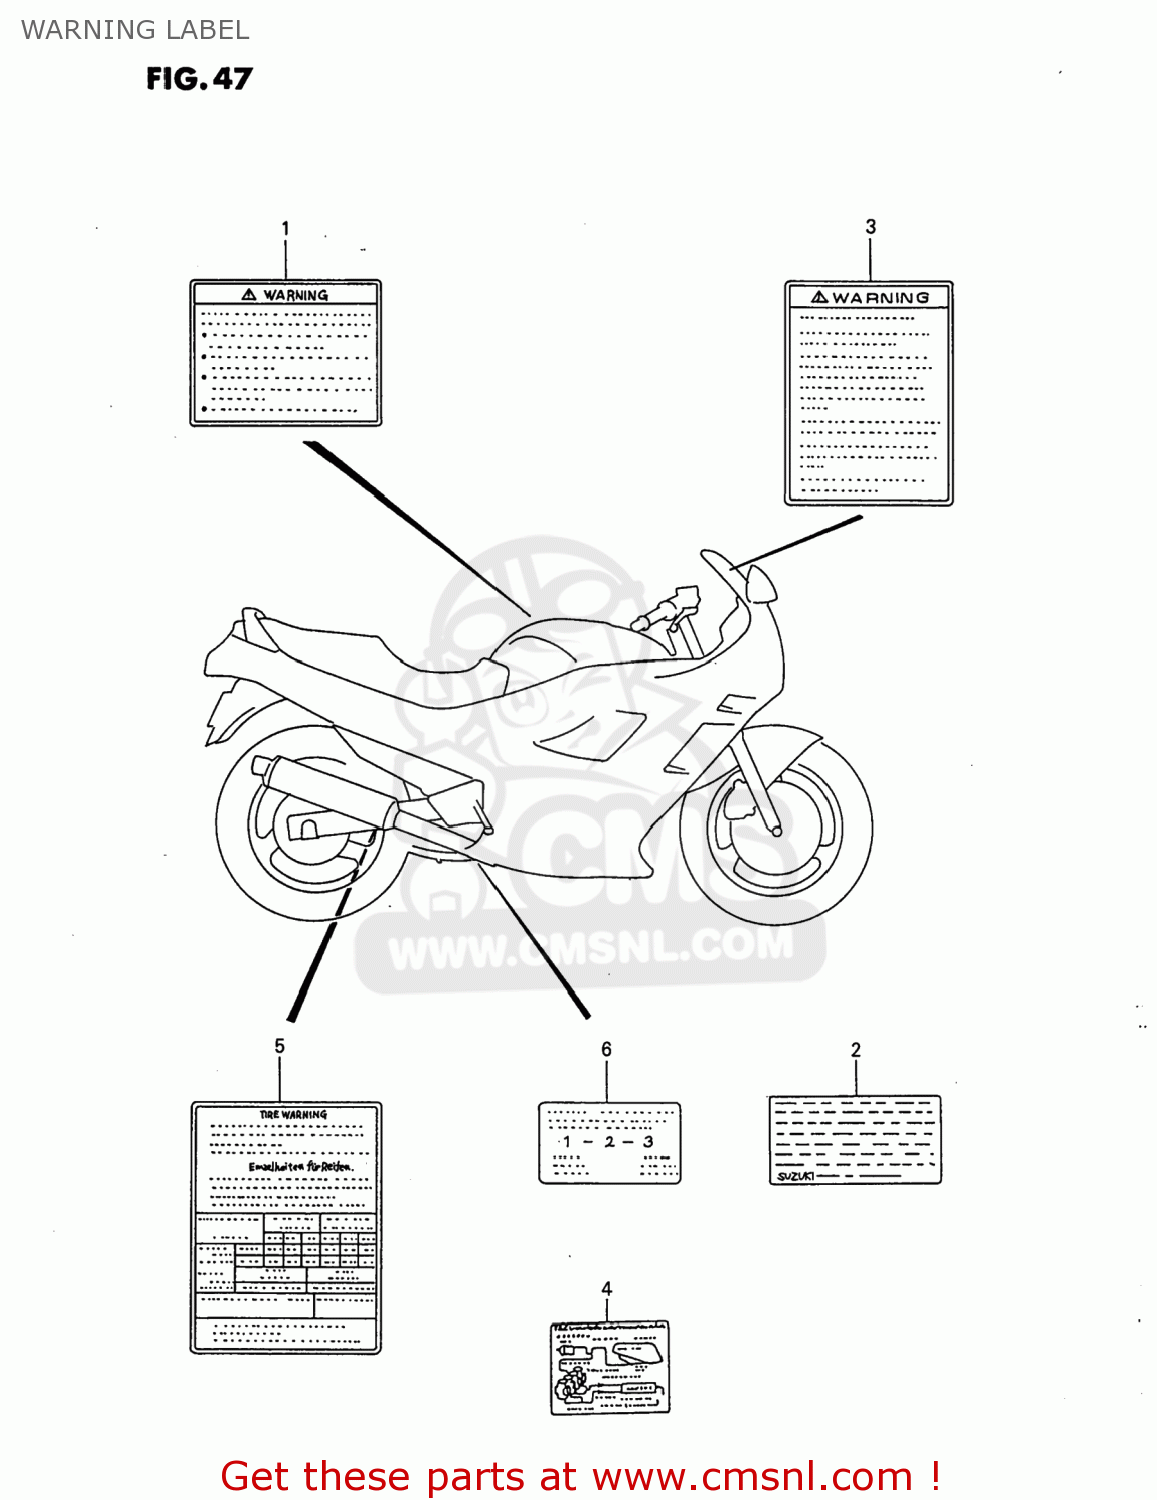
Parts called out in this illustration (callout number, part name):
1	LABEL,WARNING SAFETY
2	LABEL (MANUAL NOTICE)
3	LABEL (WARNING SCREEN)
4	LABEL (VACUUM HOSE ROUTING)
5	LABEL, TIRE AIR
6	LABEL (REAR SHOCK ABSORBER)
7	MANUAL, OWNER'S
